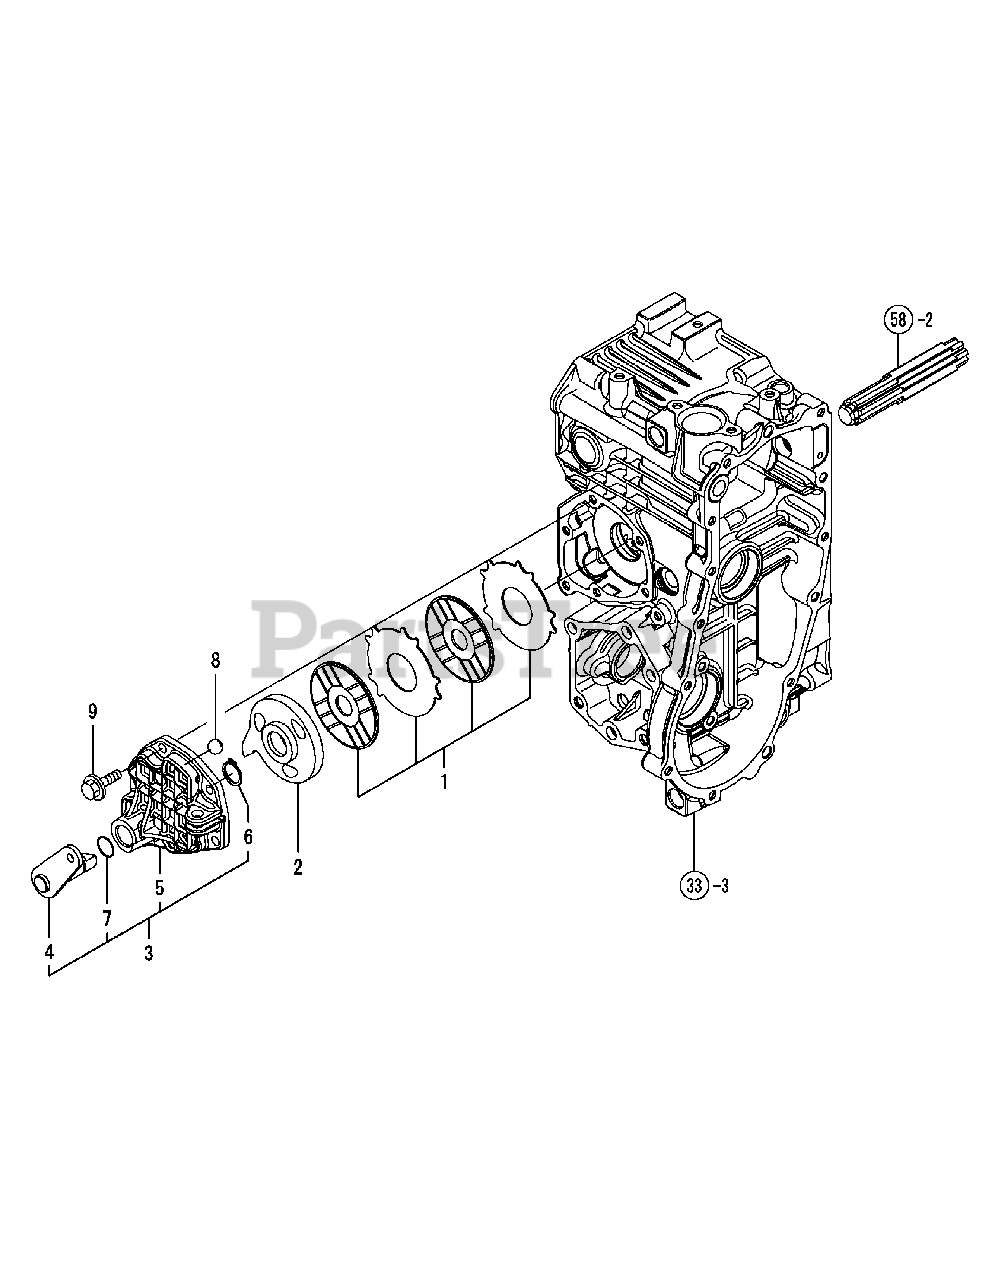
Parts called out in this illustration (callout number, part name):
1	PLATE KIT, BRAKE
3	CAM KIT, BRAKE
4	SHAFT ASSY, LEVER
7	O-RING 1A P-16.0
9	BOLT M 8X 25 PLATED
